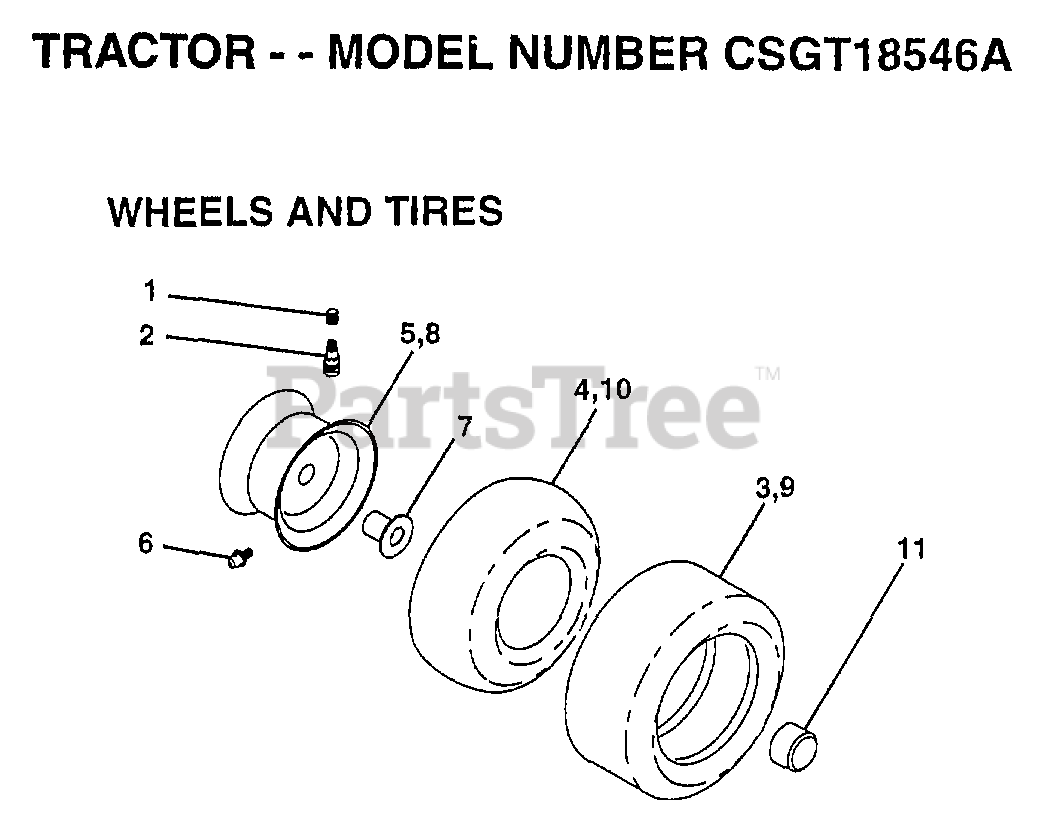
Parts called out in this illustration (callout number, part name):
1	VALVE CAP
2	VALVE STEM LT
4	TUBE.5.3/4.5/6
5	"RIM ASM 8"" FRT"
6	FITTING LT
7	"FLANGE, BEARING"
8	RIM.REAR.
10	TUBE.23X8/10-12
11	HUB CAP
